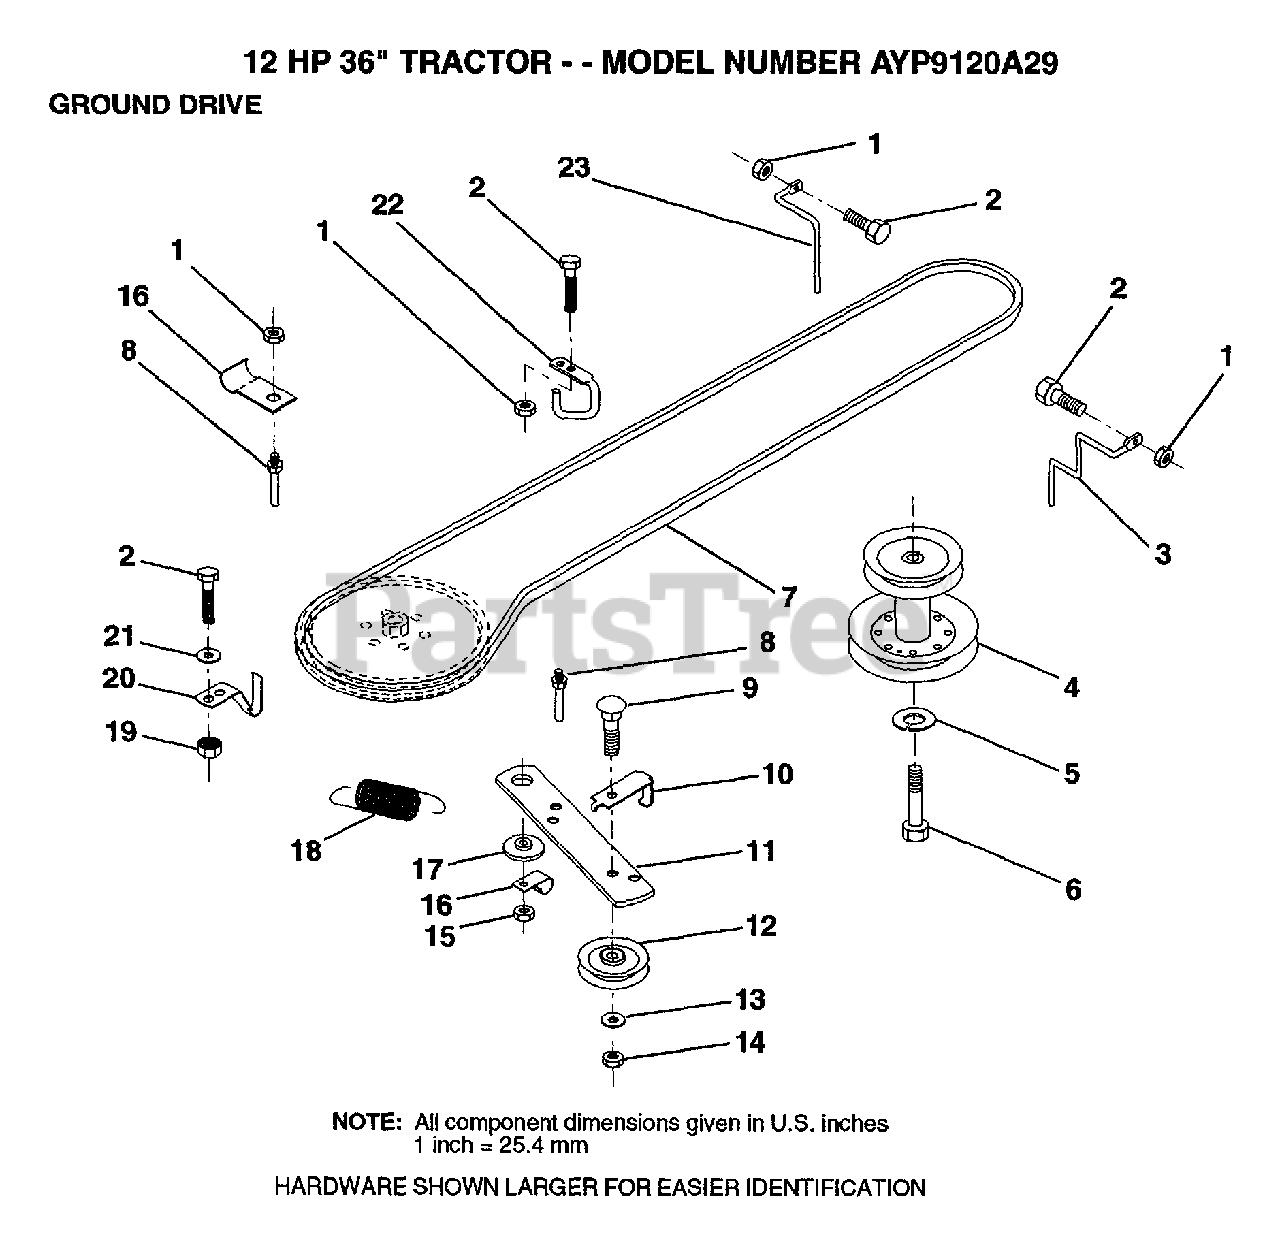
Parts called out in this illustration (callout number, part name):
2	BOLT
5	LOCKWASHER
6	HEX BOLT
7	BELT
8	"KEEPER,DRIVE BELT"
9	BOLT
10	"KEEP,IDLER DR BEL"
13	WASHER
14	LOCKNUT
16	"CLIP,INSULATOR"
17	SPACER RETAINER
20	"KEEPER,DR BELT "
21	WASHER
22	"KEEPER,FRA DR BEL"
